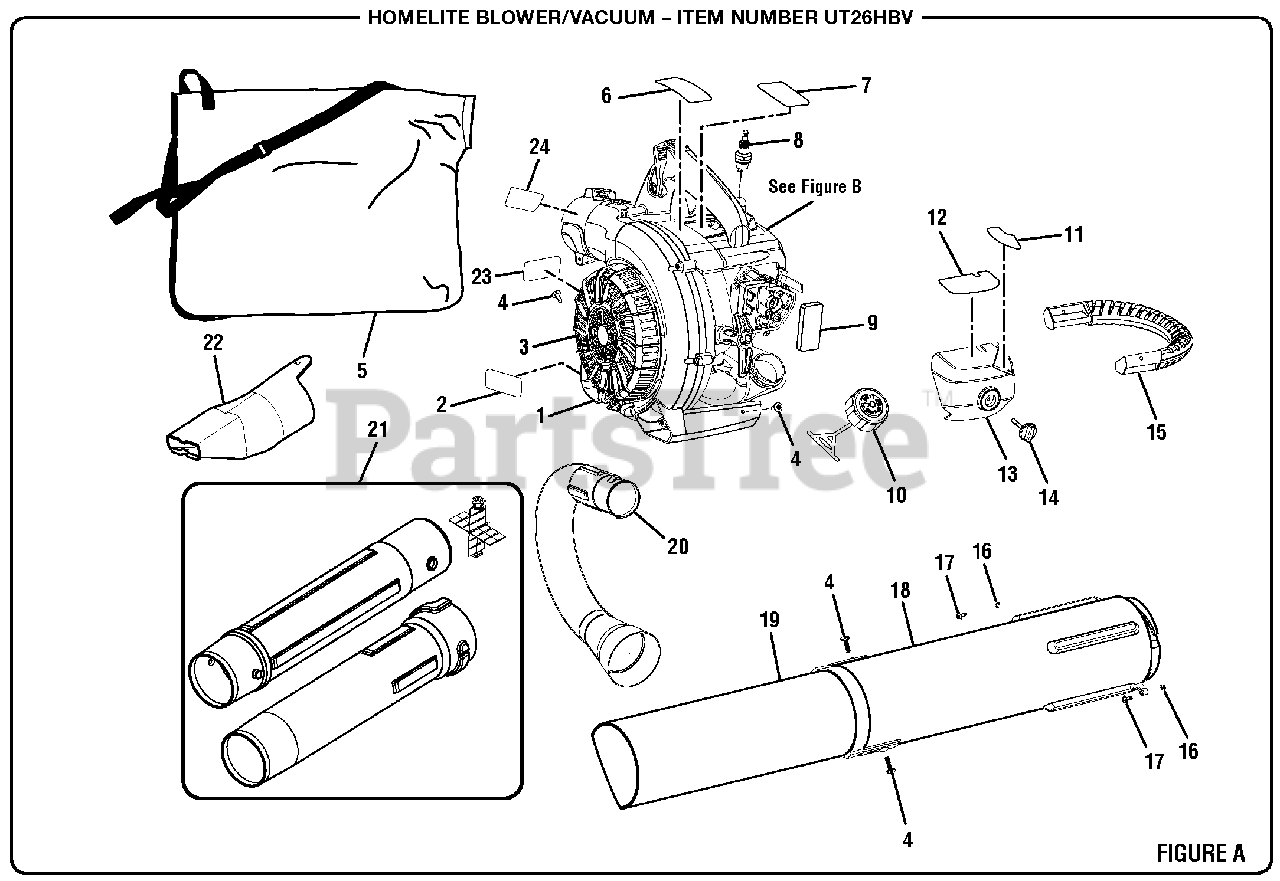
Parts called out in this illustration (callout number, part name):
1	Vacuum Door Spring
2	Combustion Label
3	Vacuum Door
4	Vacuum Tube Screw (10-14 x 1/2 in.)
5	Vacuum Bag w/Shoulder Strap
6	Warning Label
7	Logo Label (Small)
8	Spark Plug (L7RTC)
10	Fuel Cap Assembly
11	Choke Label
12	Starting Label
13	Air Filter Cover
15	Vacuum Handle
17	Screw (1/4-20 x 3/4 in.)
18	Upper Vacuum Tube
19	Lower Vacuum Tube
20	Vacuum Bag Adaptor
21	Blower Tube Assembly
22	Wet Leaf Nozzle
23	Hot Surface Label
24	Tube Removal Label
